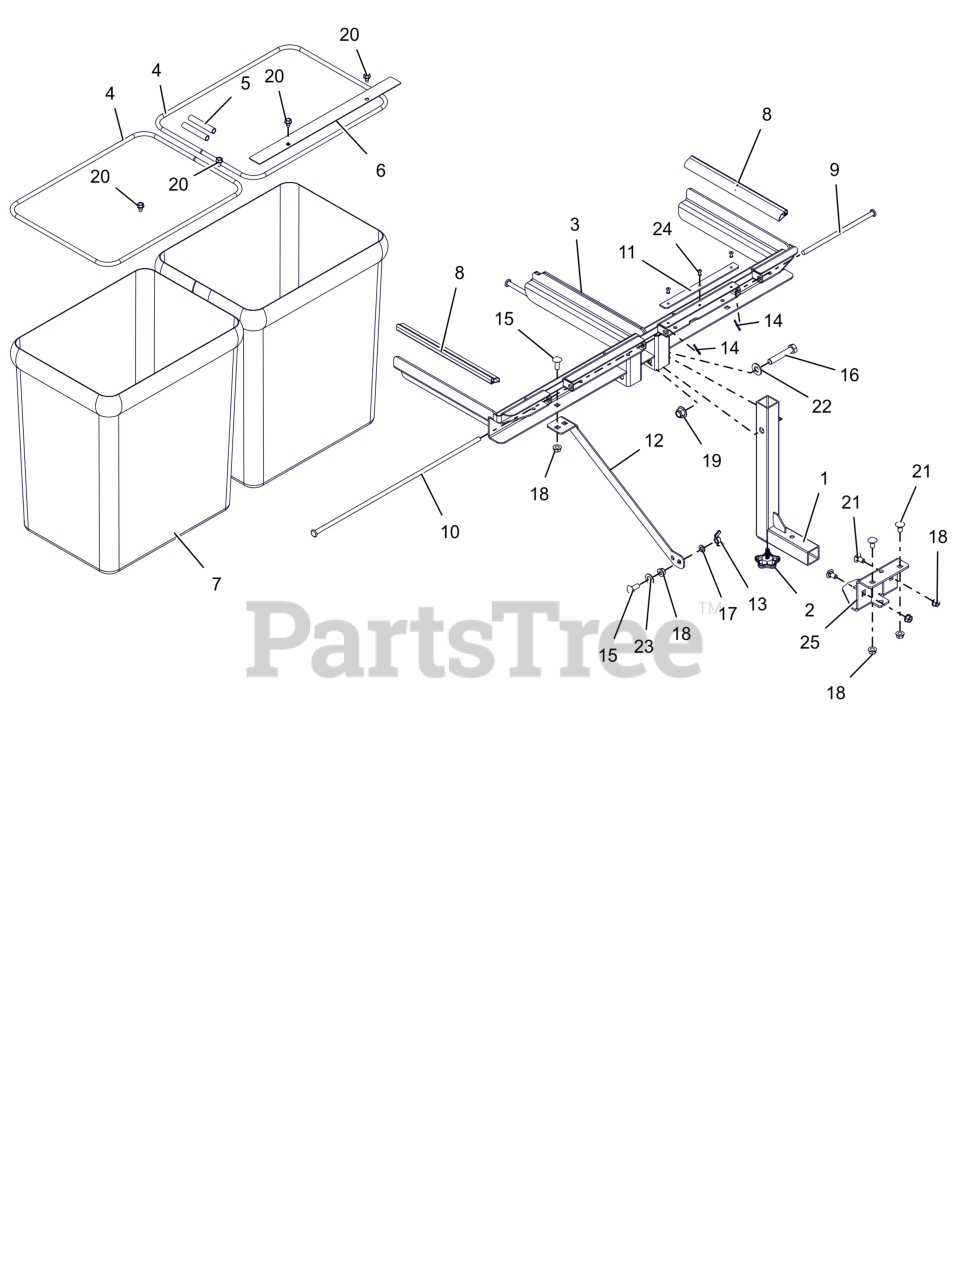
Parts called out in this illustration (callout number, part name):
1	WLDMT, BAGGER MOUNT POST(2BKT)
2	KNOB, WING STUDDED
3	ASS'Y, BAGGER FRAME UPPER
4	FRAME, ZOOM BAG
5	HOSE, .38 X.50 X 3.00 VINYL
6	BRKT-BAGGER OVERLAP
7	BAG, MESH ZOOM
8	SEAL, BULK
9	PIN, BAGGER HINGE (L)
10	PIN, BAGGER HINGE (R)
11	SEAL, HINGE
12	BRACKET, BAGGER SUPPORT (EXT)
13	NUT-WING .375-16 ZCC
14	PIN, HAIR #225 .072X1.09
15	BLT,RHSSN .38-16X1.00 G5 ZCC
16	BLT, HEX .50-13X2.75 G8 ZCC
17	WSHR,LK-REG .375X.094 ZCC
18	NUT-LK-TOP-FLG .38-16 ZC120
19	NUT,NYL-FLG .50-13 GF ZCC
20	SCR,TAP .312-18X.50 HWH TR ZCC
21	BLT, RHSN .38-16X.750 G5 ZCC
22	WSHR, FLT .531X1.250X.100 ZCC
23	WSHR, FLT .505X1.00X.062 ZCC
24	RVT-POP.187X.527 DOME ST
25	BRKT, HITCH TONGUE
